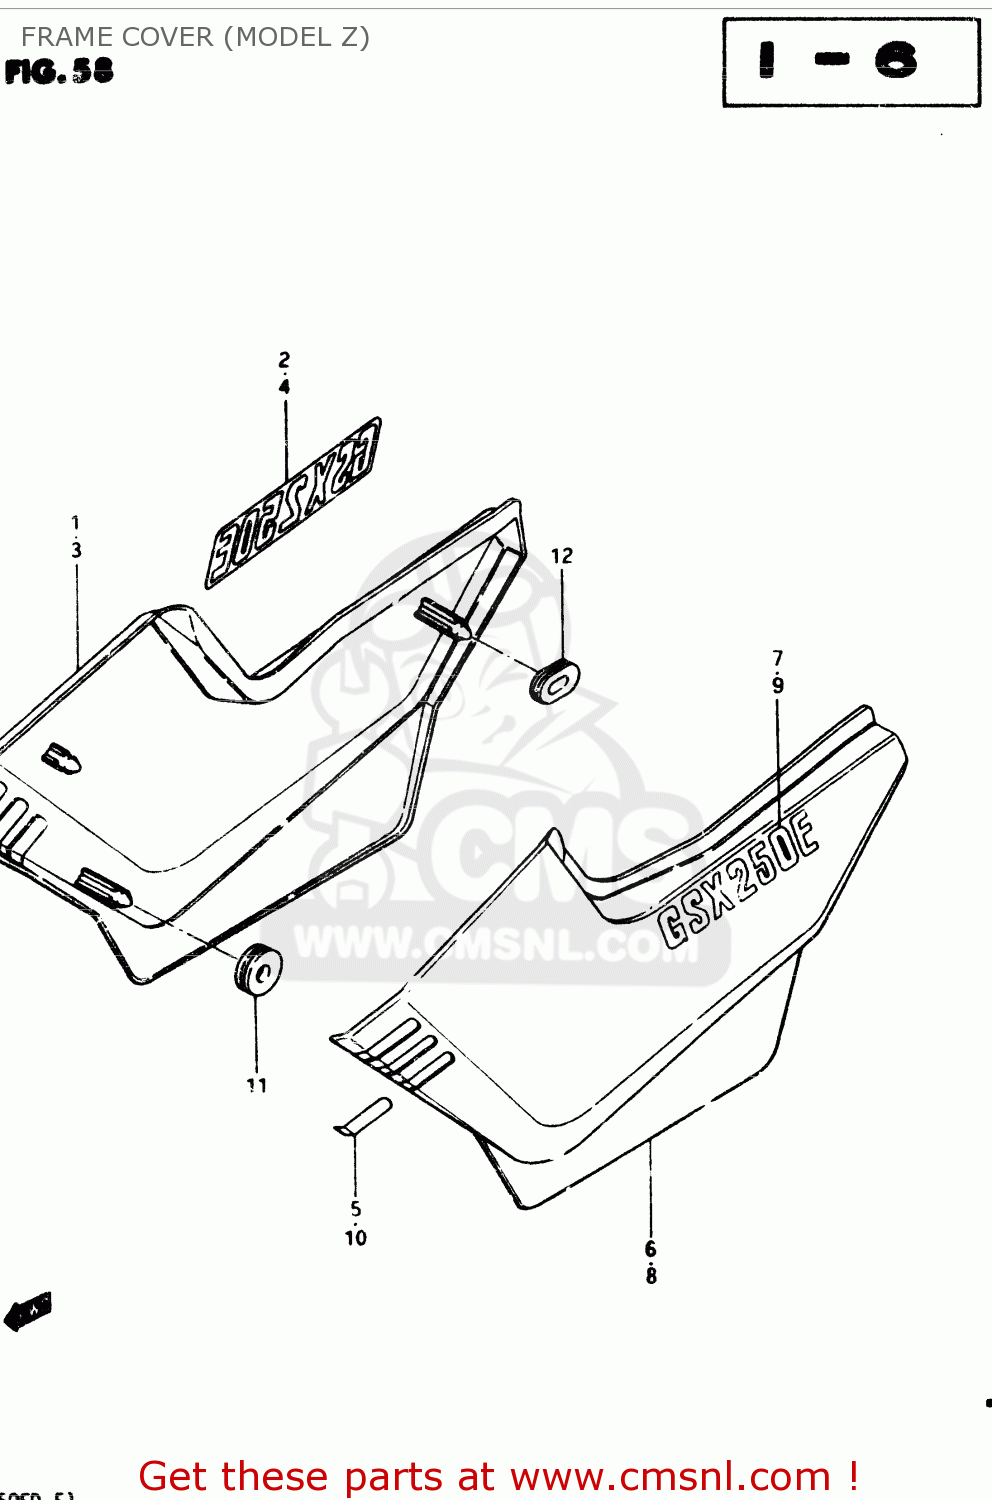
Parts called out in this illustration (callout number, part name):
1	COVER, FRAME RH (RED)
2	EMBLEM, LH
3	COVER, FRAME RH (SILVER)
4	EMBLEM
5	LABEL,FRAME COVER DENT
6	COVER, FRAME LH (RED)
7	EMBLEM, LH
8	COVER, FRAME LH (SILVER)
9	EMBLEM
10	LABEL,FRAME COVER
11	CUSHION
12	CUSHION
